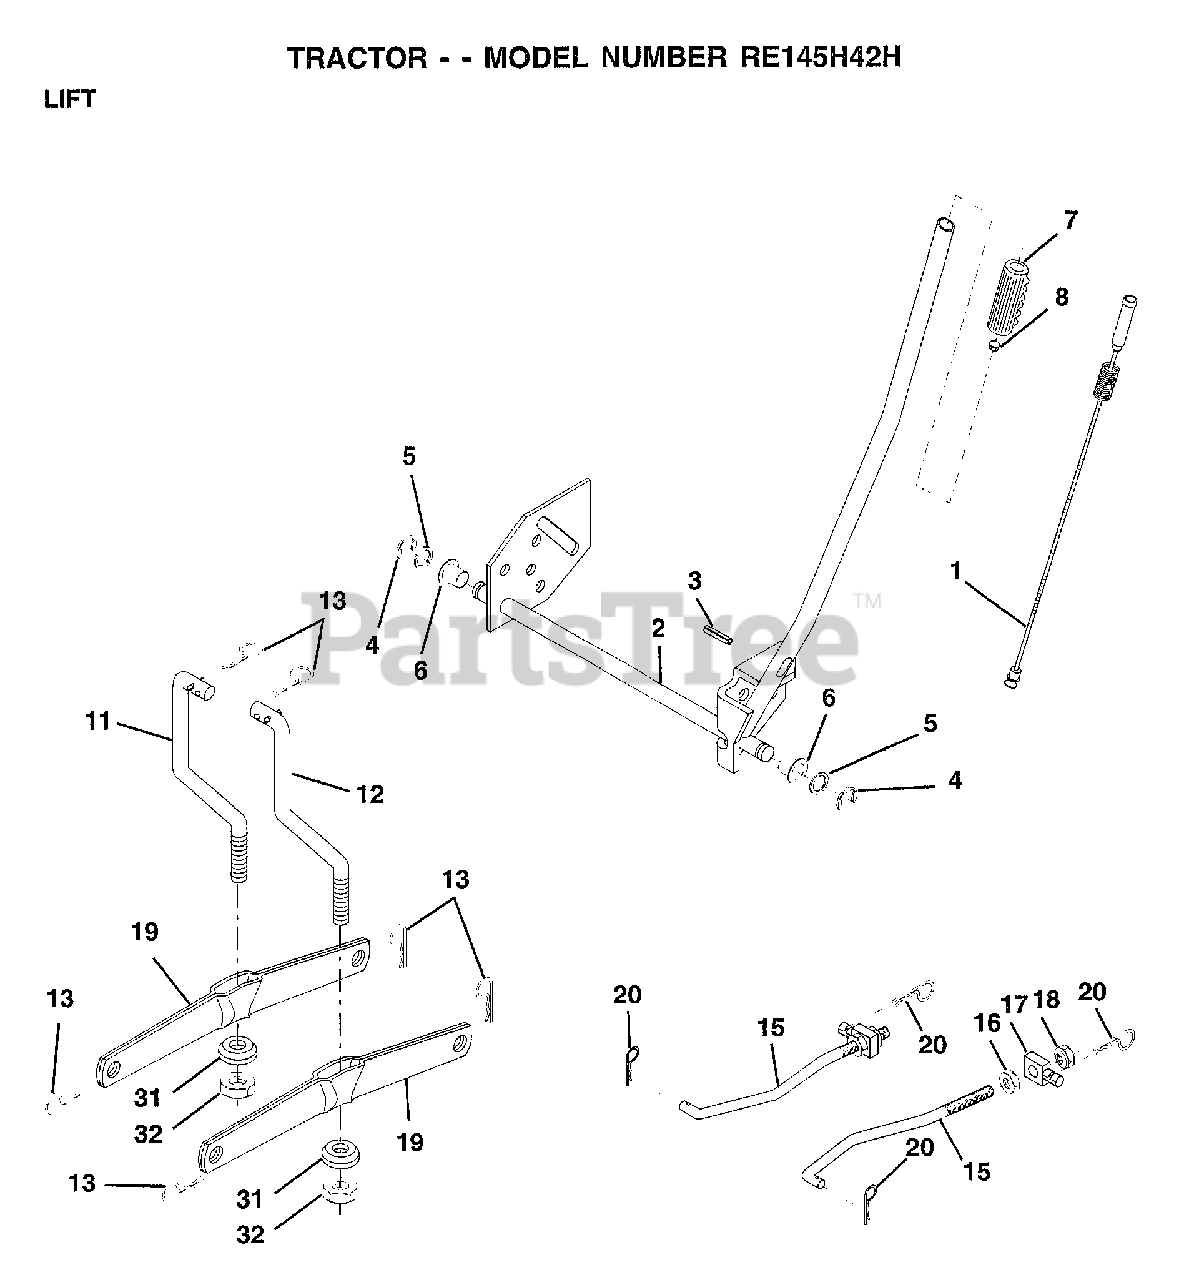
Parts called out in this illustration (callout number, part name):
1	WIRE ASM W.SPRING
2	"SHAFT ASM LIFT,RH"
3	PIN-GROOVE LT
5	WASHER
6	NYLON BEARING
7	GRIP
15	LINK, FRONT
16	NUT
17	TRUNION
18	NUT.LK.W/WSH.1/2.
19	ARM SUSP REAR
20	RETAINER SPRING
31	BEARING PVT LH
32	NUT.CROWNLOCK.3/8
